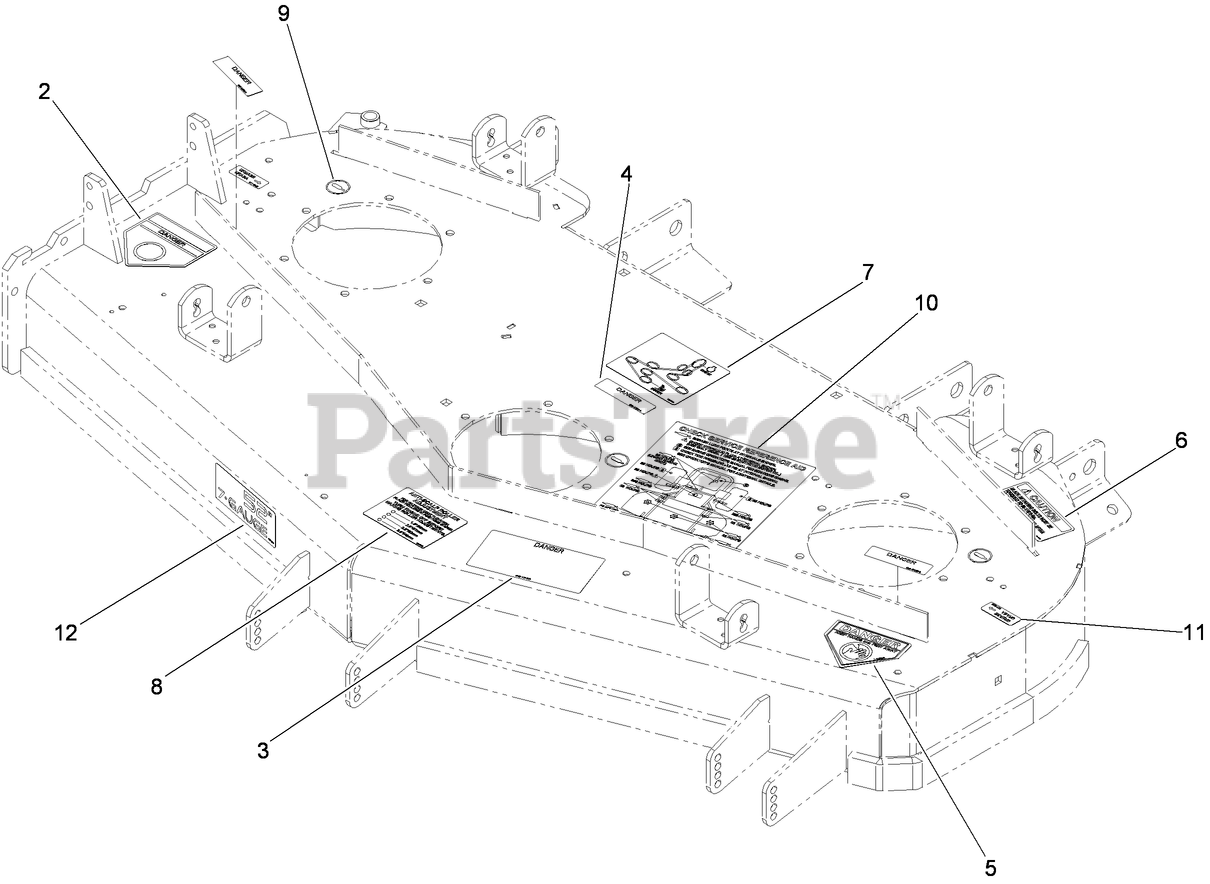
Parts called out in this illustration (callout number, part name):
2	DECAL-DANGER
3	DECAL-DANGER, THROWN OBJECT
4	DECAL-COVER, MISSING
5	DECAL-DANGER
6	DECAL-TORQUE
7	Decal-Routing, Belt
8	DECAL-SCALP, ANTI
9	DECAL-GREASE
10	DECAL-SERVICE, CHECK
11	Decal-Grease
